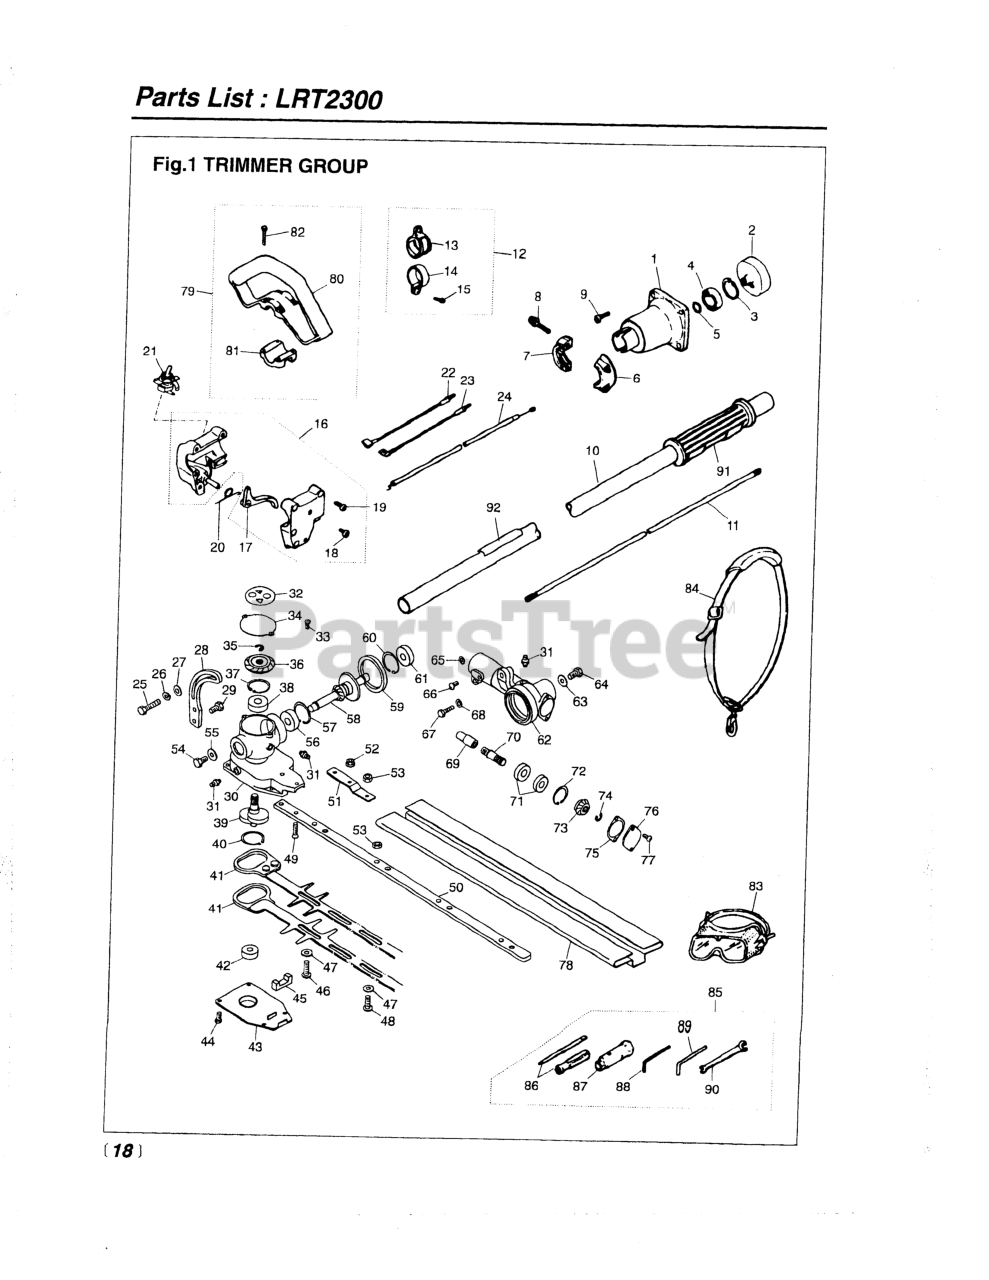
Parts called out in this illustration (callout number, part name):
3	RING, SNAP, M28 x 1.2
4	BEARING
5	RING, SNAP (RPLS 3130-13270)
6	CLAMP, LEFT
7	CLAMP, RIGHT
8	BOLT
9	BOLT, M6 x 20
12	HANGER COMPLETE
13	HANGER
14	CLAMP
15	SCREW, M5 x 25
17	LEVER, THROTTLE
18	SET SCREW, ANTI-ROTATION
19	SCREW
20	SPRING, THROTTLE TRIGGER
21	SWITCH, STOP
22	CORD, RED (LEAD WIRE)
23	CORD, BLACK (LEAD WIRE)
24	CABLE COMP
26	WASHER, M6 X 15
27	WASHER, 6 X 6 X 2.0
28	ADJUSTER, ANGLE (USE-13141)
31	FITTING, GREASE
33	SCREW, M4 X 8
35	RING, SNAP
36	GEAR, BEVEL
37	RING, SNAP, M26 X 1.2
38	BEARING
39	CRANKSHAFT
40	RING, SNAP, M28 X 1.5
42	BEARING
44	BOLT, M4 X 8
45	FELT
47	WASHER (RPLS 3873-11760)
48	SCREW
49	SCREW, M5 X 20
50	PLATE, GUIDE
51	PLATE (RPLS 6780- )
52	NUT, M5
53	NUT, M6
55	WASHER, 6X15X2.0
56	BEARING
57	RING, SNAP, M22 x 1.2
59	O-RING
60	RING, SNAP, M26 X 1.2
61	BEARING
62	CASING
63	WASHER, 6 X 6 X 2.0
65	WASHER
66	SCREW, M5 x 10
67	BOLT, M5 x 25
68	WASHER, M5 x 10
69	JOINT (REPLACES T3078-13810)
70	SHAFT, GEAR
71	BEARING
72	RING, SNAP, M22 x 1.2
73	GEAR, BEVEL
74	RING, SNAP
75	PACKING
76	COVER, STOPPER KIT
77	SCREW, M4 X 8
78	COVER, BLADE
79	HANDLE ASSEMBLY
80	HANDLE
81	CLAMP
82	SCREW, M5 x 35
83	GOGGLE
84	SHOULDER STRAP ASSY
85	TOOL SET
86	SCREWDRIVER
88	WRENCH (TOOL)
89	BAR
90	SPANNER, 8 X 10 (RPLS 2540- )
92	DECAL
